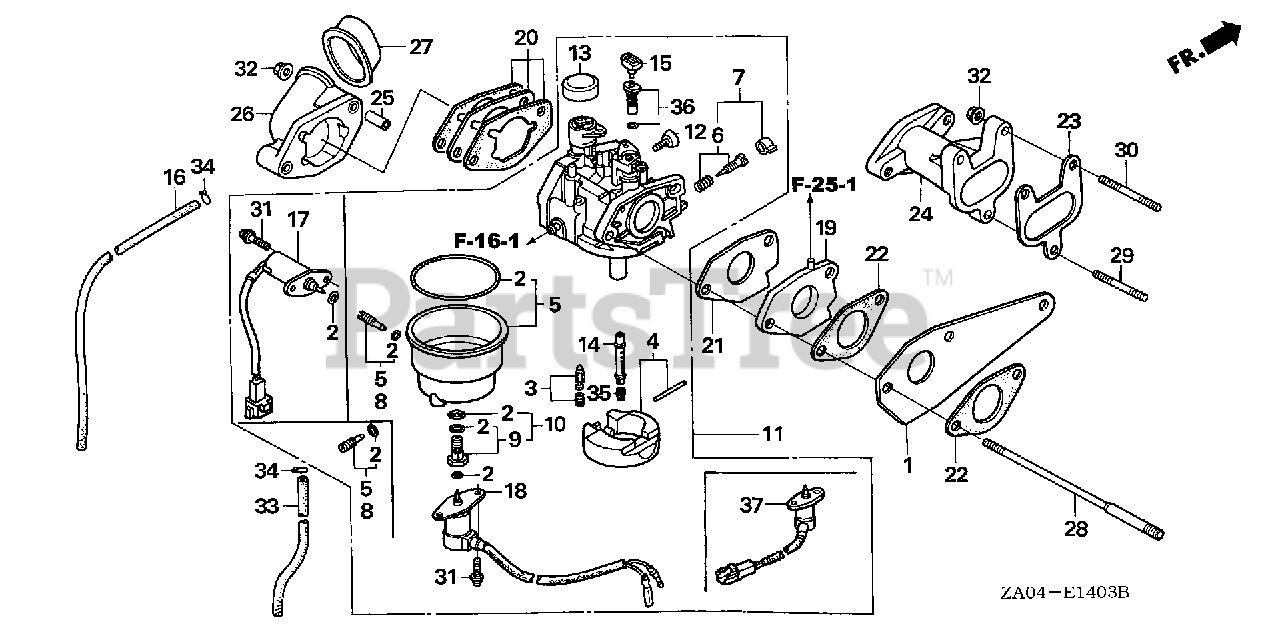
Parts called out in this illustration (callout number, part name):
1	STAY, TIMING BELT
2	GASKET SET (CARBURETOR NO.)
3	VALVE SET, FLOAT
4	FLOAT SET
5	CHAMBER SET, FLOAT (CARBURETOR NO.)
7	SCREW SET (Honda Code 4219879). (CARBURETOR NO.)
8	SCREW SET, DRAIN (ADVENTURE GREEN) (CARBURETOR NO.)
10	SCREW SET
11	CARBURETOR ASSY. (BE77J B)
12	SCREW, THROTTLE STOP
13	CAP, CHOKE LEVER DUST
14	NOZZLE, MAIN
15	COLLAR, SET
16	TUBE, AIR VENT
17	VALVE ASSY., SOLENOID (CARBURETOR NO.)
19	INSULATOR, CARBURETOR
20	SPACER, CARBURETOR
21	GASKET, CARBURETOR
22	GASKET, INSULATOR
23	GASKET, IN. MANIFOLD
24	MANIFOLD, IN.
25	COLLAR, AIR CLEANER
26	ELBOW, AIR CLEANER
27	BUSH, AIR CLEANER ELBOW
28	BOLT, STUD (8X132)
29	BOLT, STUD (6X32)
30	BOLT, STUD (6X28)
31	SCREW-WASHER (5X12)
32	NUT, FLANGE (6MM)
33	BULK HOSE, FUEL (4.5X3000) (Honda Code 5137104). (4.5X140)
34	CLIP, TUBE (B8)
35	JET, MAIN (#90) Use from Engine SN BE81B C.
35	JET, MAIN (#92)
35	JET, MAIN (#95)
36	JET SET, PILOT (#40) (ADVENTURE GREEN) (CARBURETOR NO.)
